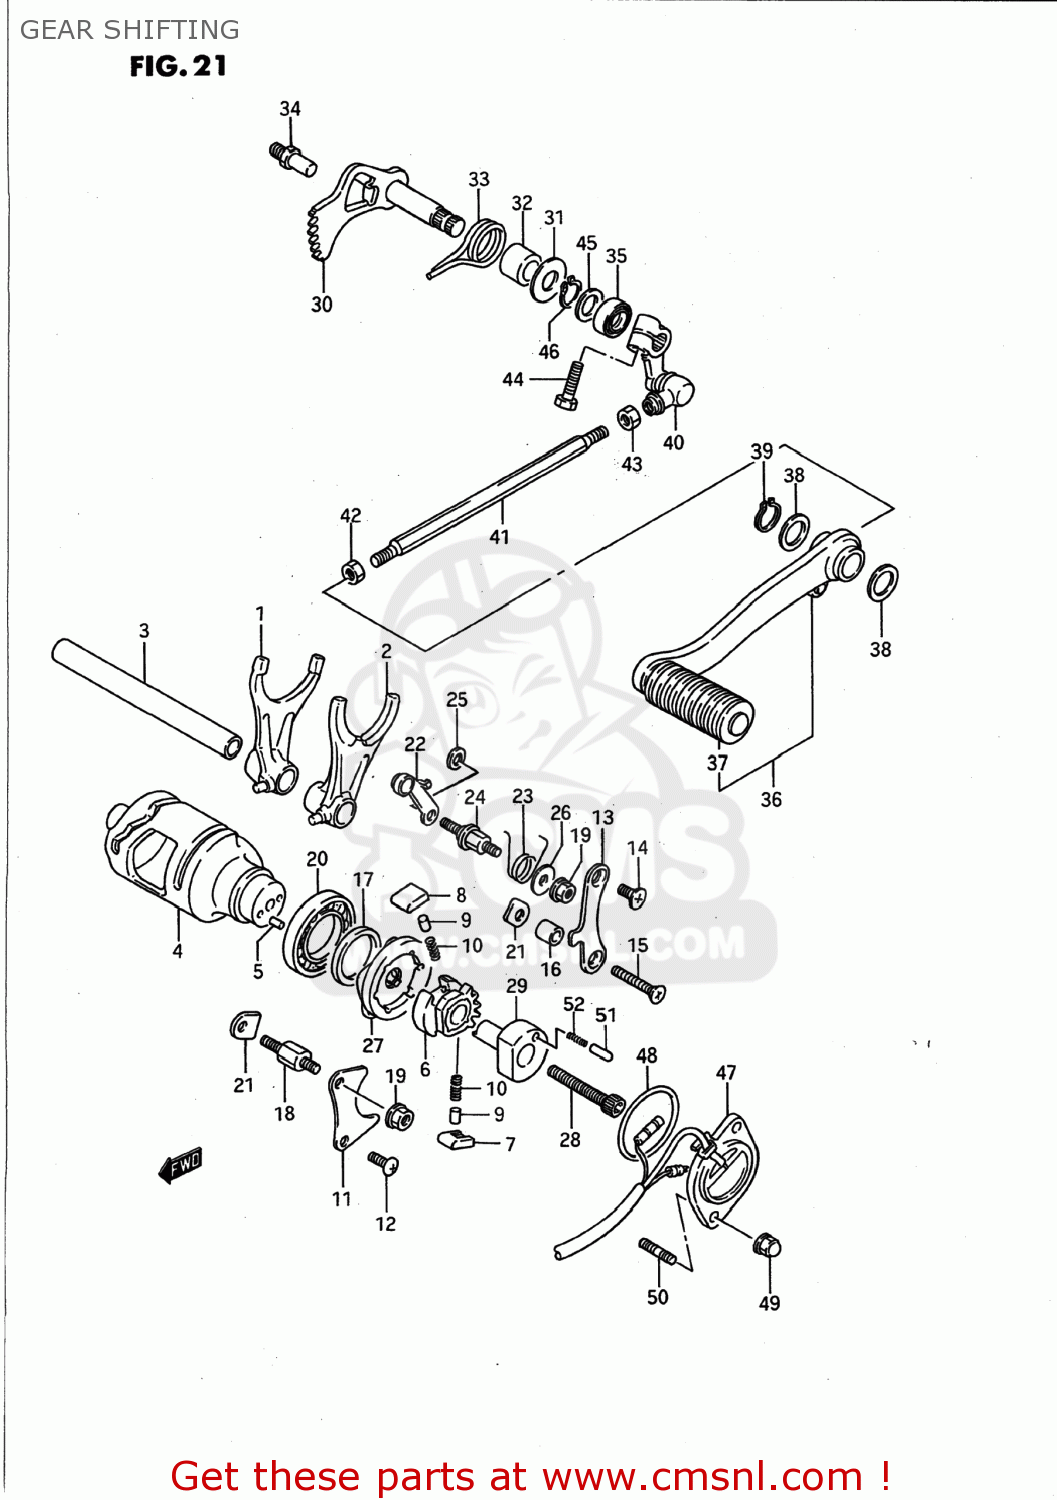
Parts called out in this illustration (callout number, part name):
1	FORK,GEAR SHIFT NO.1
2	FORK,GEAR SHIFT NO.2
3	SHAFT,GEAR SHIFT FORK
4	CAM,GEAR SHIFT
5	PIN
6	GEAR,GEARSHIFT CAM DRIVE
7	PAWL,GEAR SHIFT NO.1
8	PAWL,GEAR SHIFT NO.2
9	PIN(5X8)
10	SPRING
11	LIFTER,GEAR SHIFT POLE
12	SCREW
13	GUIDE,GEAR SHIFT CAM
14	SCREW
15	SCREW
16	SPACER (6.1X10X14)
17	WASHER(25X32X3)
18	BOSS,SHIFT PAWL LIFTER
19	NUT
20	BEARING
21	RETAINER
22	STOPPER,GEAR SHIFT CAM
23	SPRING
24	SPRING,STOPPER ARM
25	WASHER
26	WASHER (6.5X18X2)
27	PLATE,GEAR SHIFT CAM
28	BOLT
29	HOLDER,NEUTRAL SWITCH
30	SHAFT,GEAR SHIFT
31	WASHER (12.5X28X1.2)
32	SPACER(12X20X15.3)
33	SPRING
34	STOPPER,SHIFT ARM
35	OIL SEAL
36	LEVER ASSY,GEAR SHIFT
37	RUBBER,GEAR SHIFT PEDAL
38	WASHER (14.2X22X1)
39	CIRCLIP
40	ARM,GEAR SHIFT LINK
41	ROD,GEAR SHIFT LINK
42	NUT
43	NUT
44	BOLT
45	WASHER,THRUST
46	CIRCLIP,12 MM
47	BASE ASSY,NEUTRAL SW TERMINAL
48	O RING(D:2.4,ID:36.5)
49	NUT
50	BOLT,STUD
51	PIN
52	SPRING
